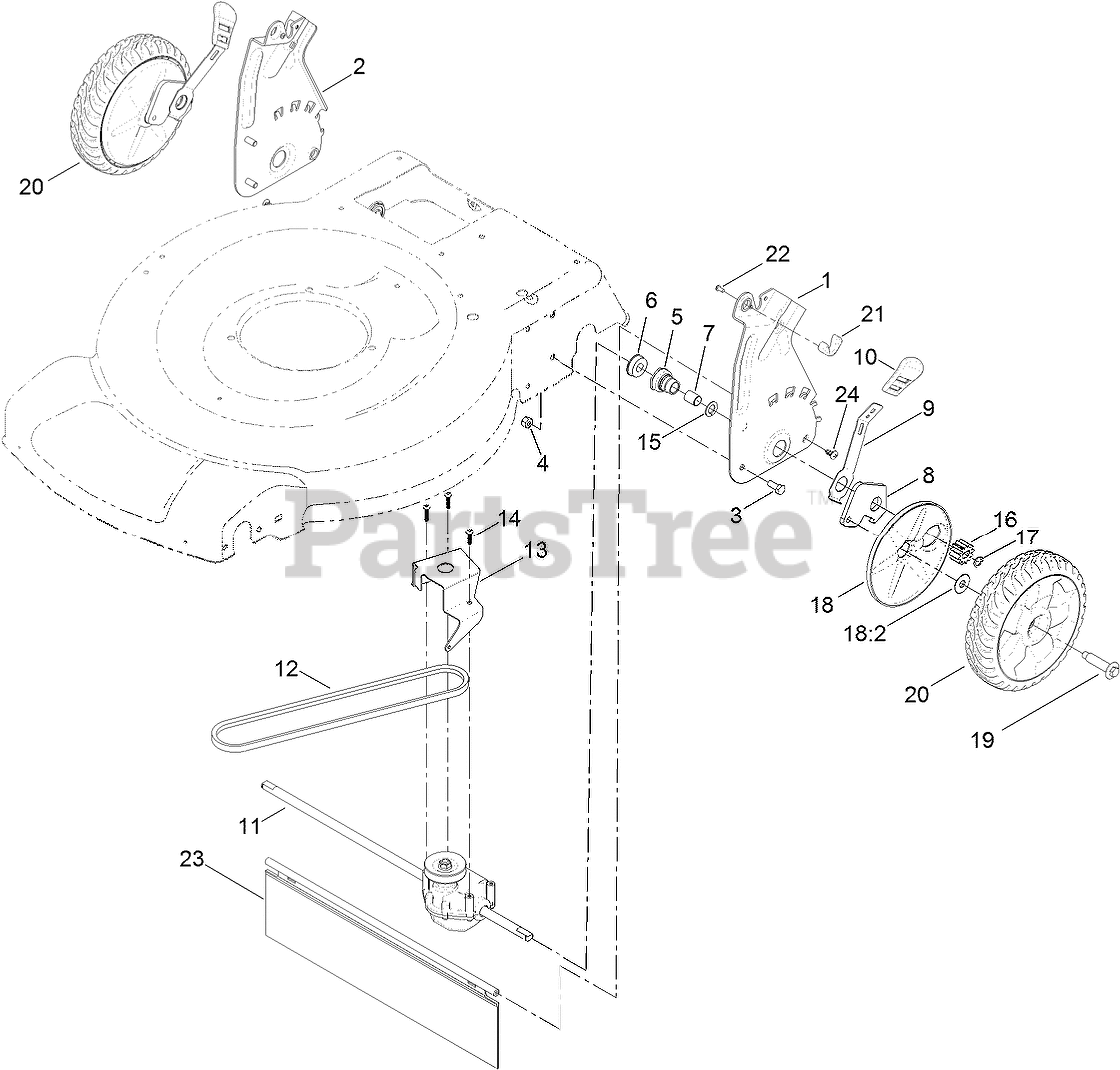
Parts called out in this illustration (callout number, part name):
1	PLATE-REAR, LH (HOC)
2	PLATE-REAR, RH (HOC)
3	SCREW-HH
4	NUT-LOCK, NI
5	RETAINER-BUSHING, HOC
6	BEARING-BALL
7	BUSHING-SLEEVE
8	ARM-PIVOT, REAR
9	ARM-SPRING
10	KNOB-HOC
11	TRANSMISSION ASM
12	BELT-V
13	BRACKET-TRANSMISSION
14	SCREW-PLASTITE
15	WASHER-THRUST
16	GEAR-PINION
17	RING-RETAINING
18	WHEEL COVER ASM
18:2	WASHER-STEPPED
19	BOLT-SHOULDER
20	8 INCH WHEEL GEAR ASM
21	ANCHOR-BAG
22	Screw-PPH
23	SHIELD-TRAILING
24	SCREW-PTH
